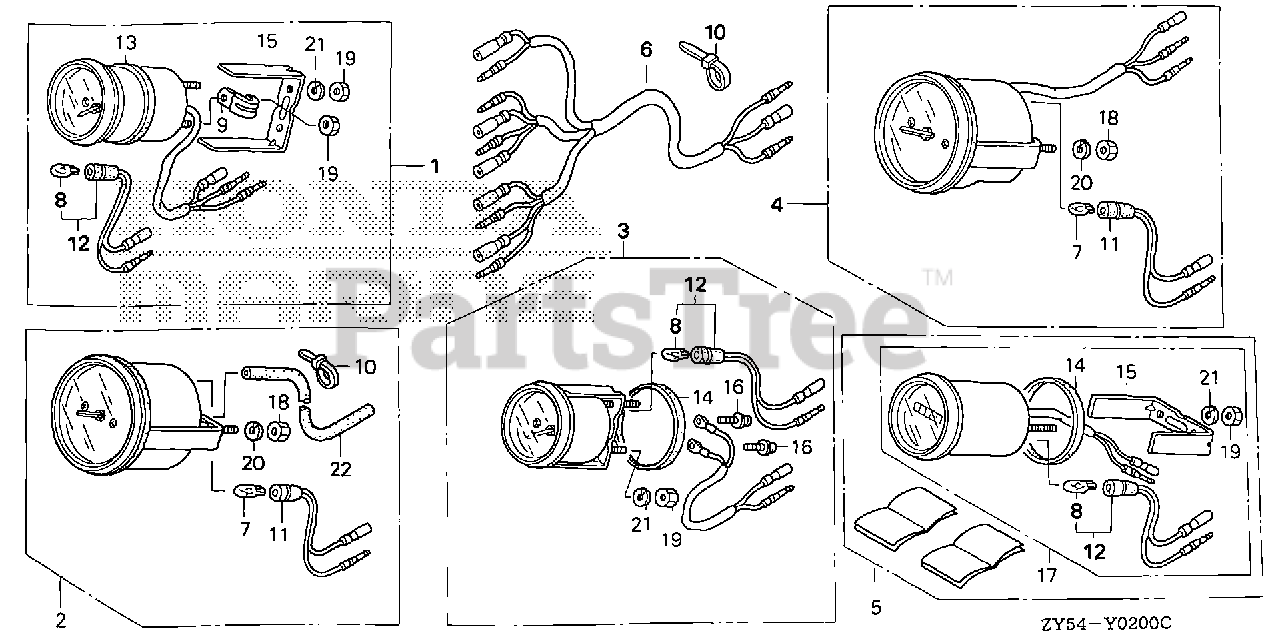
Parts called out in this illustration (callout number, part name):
1	METER KIT, TRIM
1	METER KIT, TRIM (B)
2	SPEEDOMETER KIT
2	SPEEDOMETER KIT (B)
3	METER KIT, VOLT
3	METER KIT, VOLT (B)
4	METER KIT, TACHO
4	METER KIT, TACHO (B)
5	METER KIT, HOUR (NA USE ALT:39700-ZW5-000ZA)
5	METER KIT, HOUR (B) (NA USE ALT:39700-ZW5-000ZA)
6	HARNESS ASSY., METER (B)
7	BULB, WEDGE BASE (T10) (12V 1.7W) (STANLEY)
8	BULB, WEDGE BASE (12V 1.7W)
9	CLAMP
10	BAND, SELF-LOCK
11	SOCKET
12	SOCKET
13	GASKET
14	GASKET
15	BRACKET
16	SCREW-WASHER (3X22)
17	METER ASSY., HOUR
17	METER ASSY., HOUR (B)
18	NUT, HEX. (5MM)
19	NUT, HEX. (4MM)
20	WASHER, SPRING (5MM)
21	WASHER, SPRING (4MM)
22	TUBE, SPEED METER (4X7X8000)
